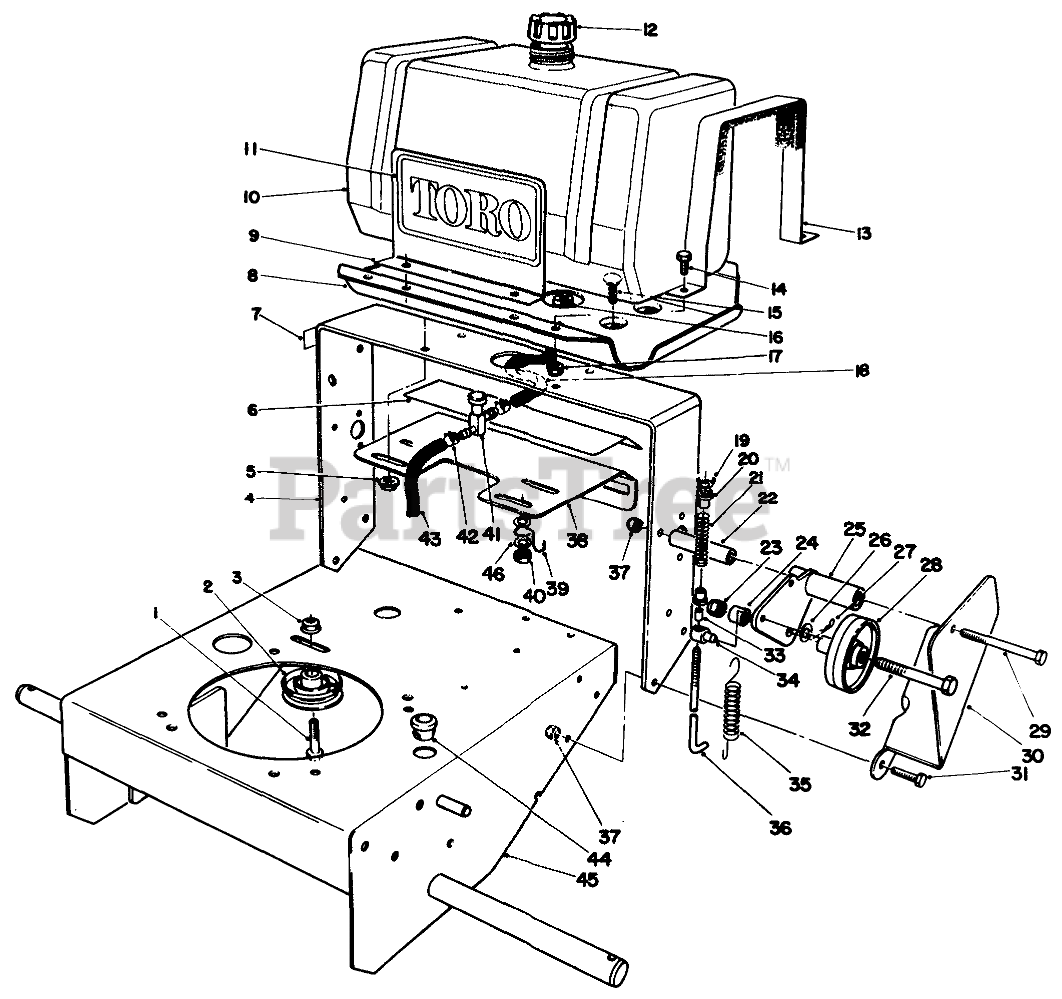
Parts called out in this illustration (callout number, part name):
1	SCREW-HH
2	PULLEY-IDLER
3	NUT-HF
4	Frame-Rear
5	NUT-HF
6	DECAL - GROUND SPEED
7	Decal-Fuel Shut Off
8	PLATE-FUEL TANK
9	DECAL-PLATE
10	TANK-FUEL
11	DECAL
12	GAS CAP ASM
13	STRAP ASM
14	SCREW-HH
15	SCREW-CARR
16	CLAMP-WORM
17	NUT-LOCK, NI
18	GAS HOSE
19	NUT-WING, LOCK
20	BUSHING-FLANGE
21	SPRING - COMPRESSION
22	PIVOT-IDLER SPACER
23	NUT-LOCK, NI
24	WHEEL IDLER SPACER
25	LH IDLER BRACKET WA R
26	WASHER-FLAT
27	PIN-COTTER
28	IdlerWheel
29	SCREW-HH
30	Bracket-LH
31	SCREW-HH
32	SCREW-HH
33	BUSHING-NYLON
34	FITTING-ROD
35	EXTENSION SPRING
36	BRAKE ROD
37	NUT-LOCK, NI
38	Plate
39	GAS LINE CLIP
40	NUT-LOCK, NI
41	FUEL VALVE
42	CLAMP-HOSE
43	GAS HOSE
44	GROMMET
45	Frame
46	WASHER-PLAIN
